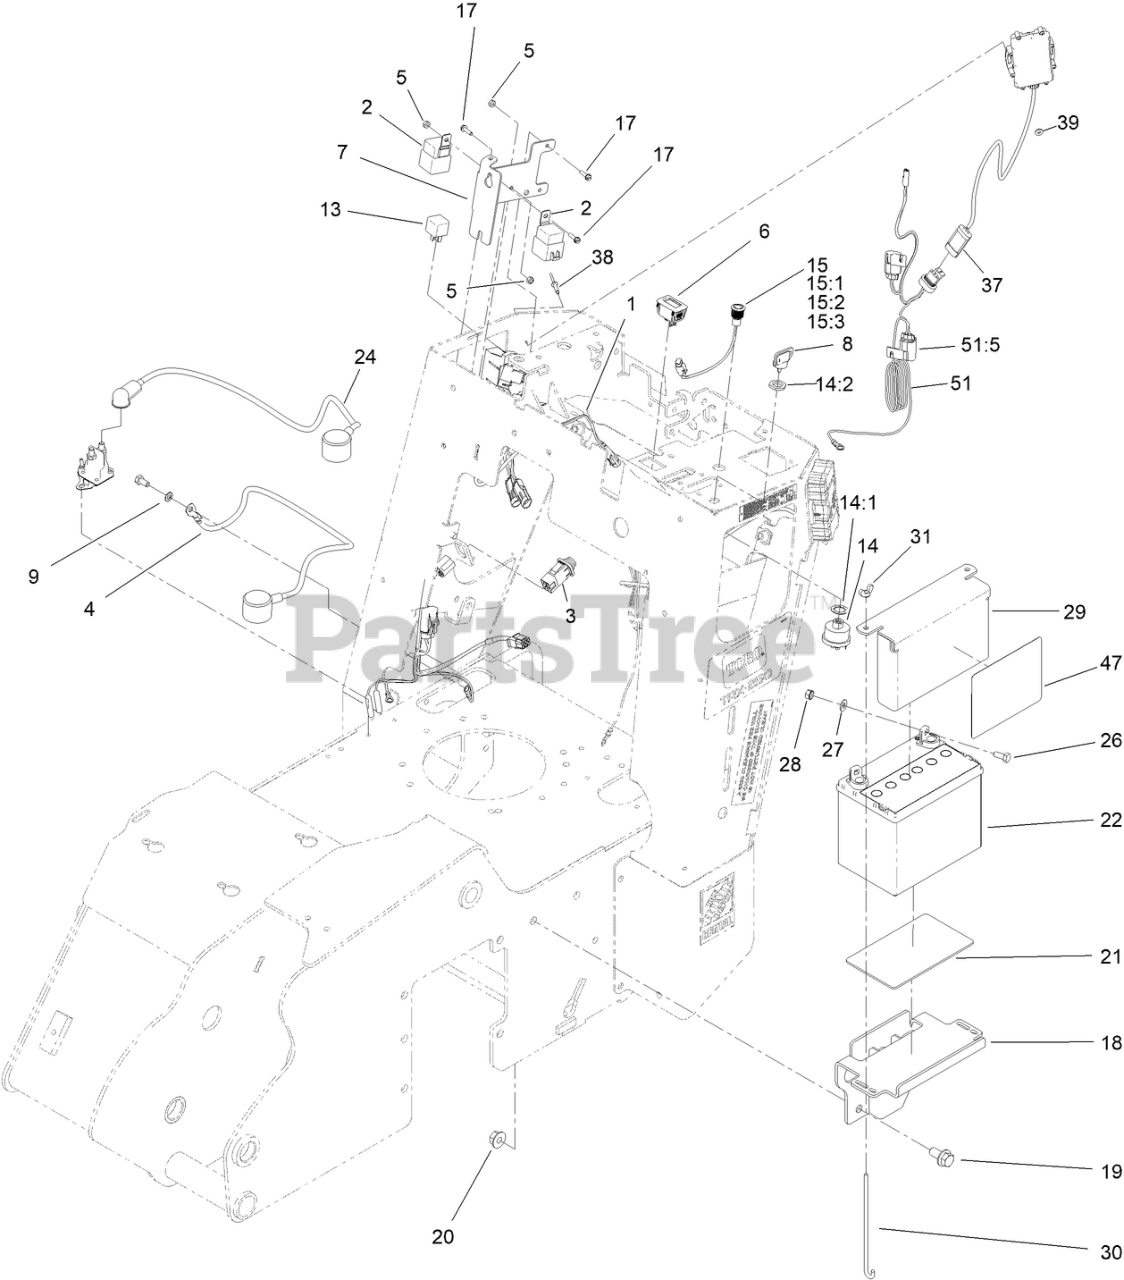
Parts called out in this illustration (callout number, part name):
1	HARNESS-WIRE, TRX
2	RELAY-MINI
3	SWITCH-PLUNGER
4	CABLE-BATTERY, NEGATIVE
5	NUT-LOCK, NI
6	HOURMETER
7	BRACKET-ELECTRICAL
8	KEY-IGNITION
9	WASHER-LOCK/EXT
13	RELAY
14:1	WASHER-LOCK
14:2	NUT-HH
15	RED LED INDICATOR LAMP ASM
15:1	GASKET-LED
15:2	WASHER-LOCKING
15:3	NUT-FIXING
17	SCREW-HWH
18	TRAY-BATTERY
19	SCREW-HHF
20	NUT-HHF
21	PAD-SKID, ANTI
22	BATTERY-DRY
24	CABLE-BATTERY, POSITIVE ASM
26	SCREW-HH
27	WASHER-FLAT
28	NUT-KEPS
29	PLATE-HOLD DOWN, BATTERY
30	BOLT-HOLDDOWN
31	NUT-WING
37	GPS ASM
38	RIVET-POP
39	WASHER-PLAIN
47	DECAL-SERVICE, TRX-300
51	HARNESS-WIRE, GPS
51:5	COVER-FUSE, SINGLE
